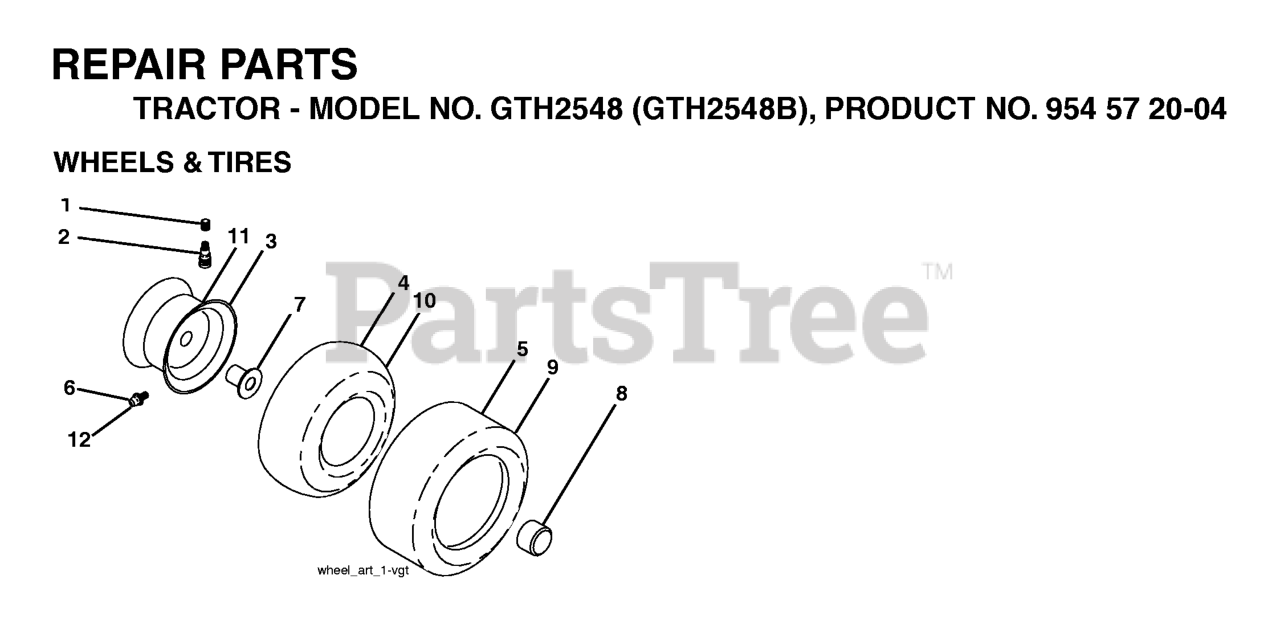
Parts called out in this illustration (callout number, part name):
2	VALVE STEM LT
3	RIM ASSEMBLY, FRONT
4	TUBE.16X6.5/7.5-8
5	TIRE HEAVY DUTY
6	FITTING LT
7	BEARING T
8	CAP, AXLE BLK
9	TIRE HEAVY DUTY
10	TUBE.23X9.5-12
11	RIM.ASM.12X7.REAR.SILVER
12	ZERK FITTING M
